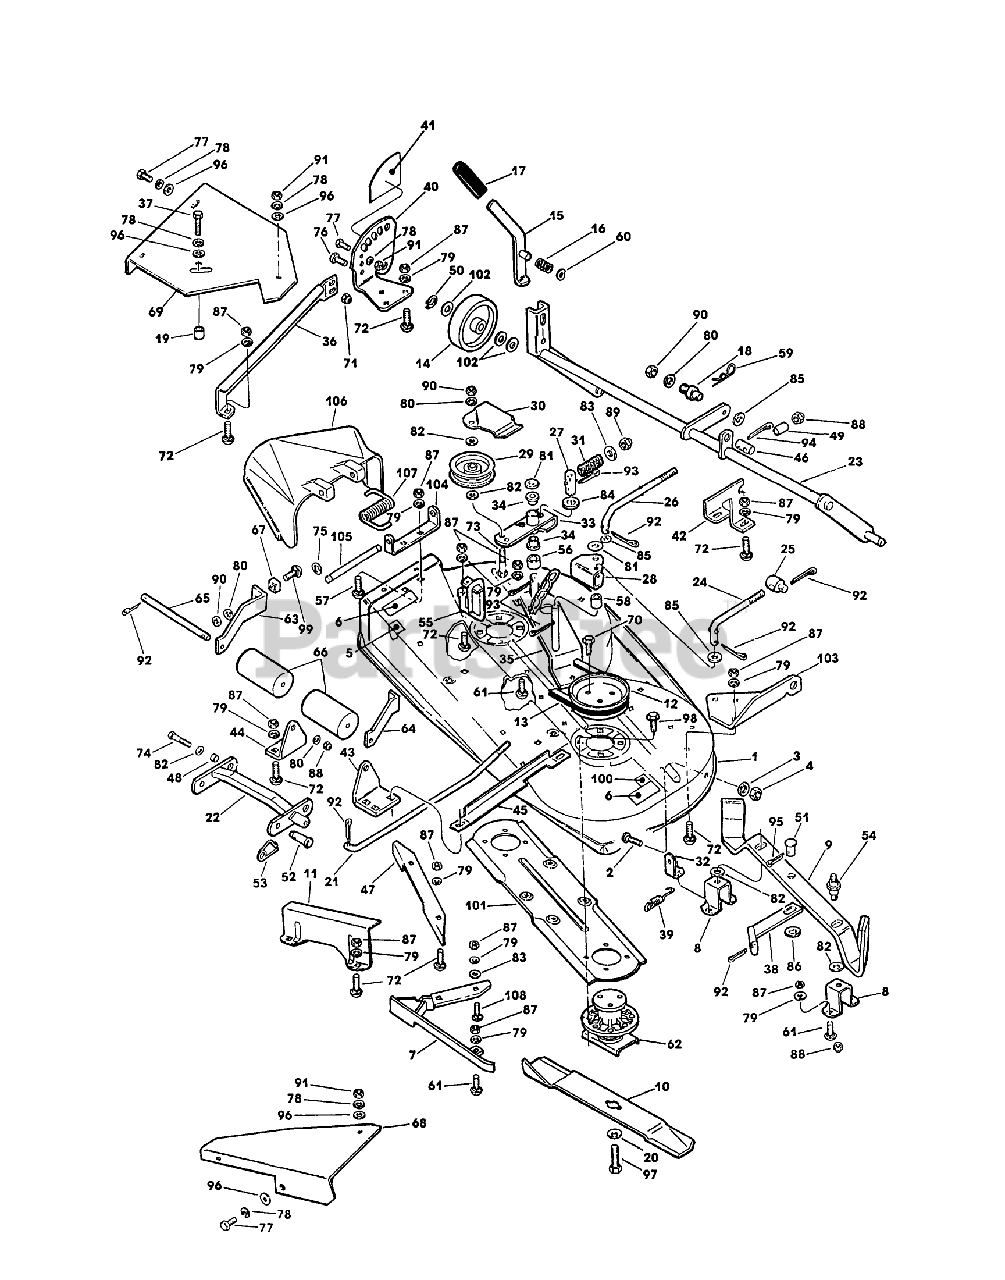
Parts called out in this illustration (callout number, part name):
4	NUT SS
6	DECAL
13	BELT
14	WHEEL
20	WASHER
21	ROD
24	ROD
26	ROD
29	PULLEY - 4"
34	BUSHING
39	SPRING
43	BRACKET
49	SPACER
50	RING - RETAINING
52	PIN CLEVIS
53	PIN - SAFETY
58	SPACER
59	PIN-HAIR
65	SHAFT
66	ROLLER
70	SCREW
71	NUT
72	BOLT - CARRIAGE
75	E-RING
76	SCREW - HEX
77	SCREW-HH
80	WASHER
82	WASHER
87	NUT SS
88	NUT-LOCKING
89	NUT
90	NUT
91	NUT
97	SCREW - HEX CAP
98	SCREW-THD ROLL, HWH
102	WASHER - SHIM
105	SHAFT - CHUTE
106	EXTENSION -CHUTE
